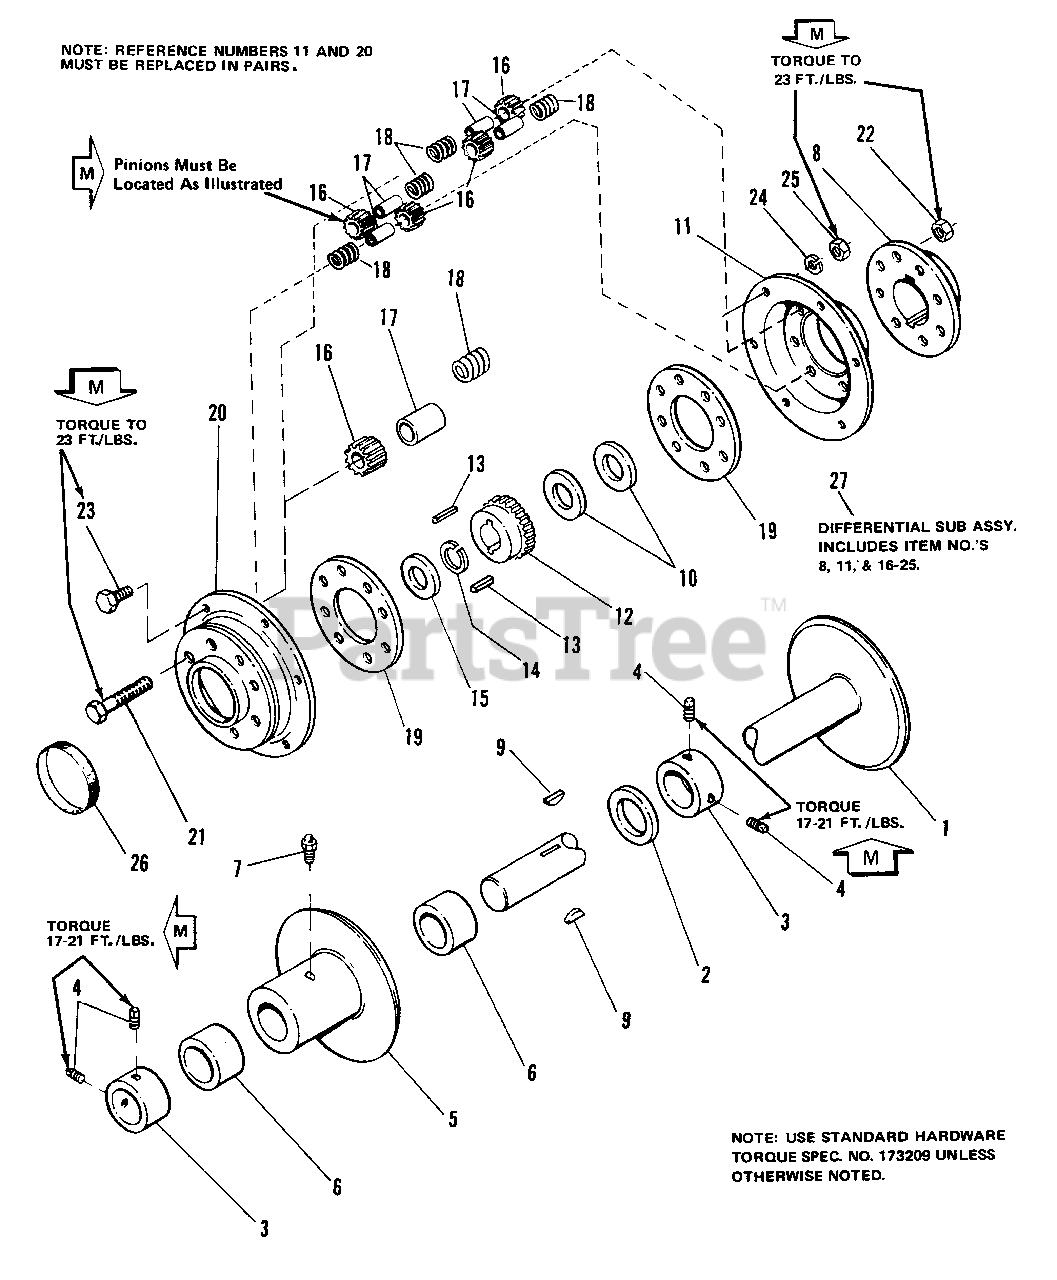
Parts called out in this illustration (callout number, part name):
1	REAR AXLE ASSEMBLY
3	COLLAR, Set
4	SETSCREW, Sq. Hd., 5/16-18 x 3/8
5	R.H. WHEEL HUB ASSEMBLY
7	FITTING, Grease
8	CARRIER, Diff.
10	WASHER, Axle
11	COVER, Diff.
12	GEAR, Diff.
13	KEY, Hi Pro, 1/4 x 3/4
14	RING, Retaining
15	WASHER, Axle
16	PINION, Diff.
17	SPINDLE, Diff. Pinion
19	RING, Spacer
20	COVER, Diff.
21	CAPSCREW, Hex Hd., 3/8-16 x 2-1/2
22	LOCKOUT, Center. 3/8-16
23	CAPSCREW, Hex, 1/4-20 x 5/8
24	LOCKWASHER, 1/4
25	NUT, Hex, 1/4-14
26	SEAL, Cover
27	DIFFERENTIAL SUB ASSY., (Includes Item Nos 8, 11, 16 thru 25)9
